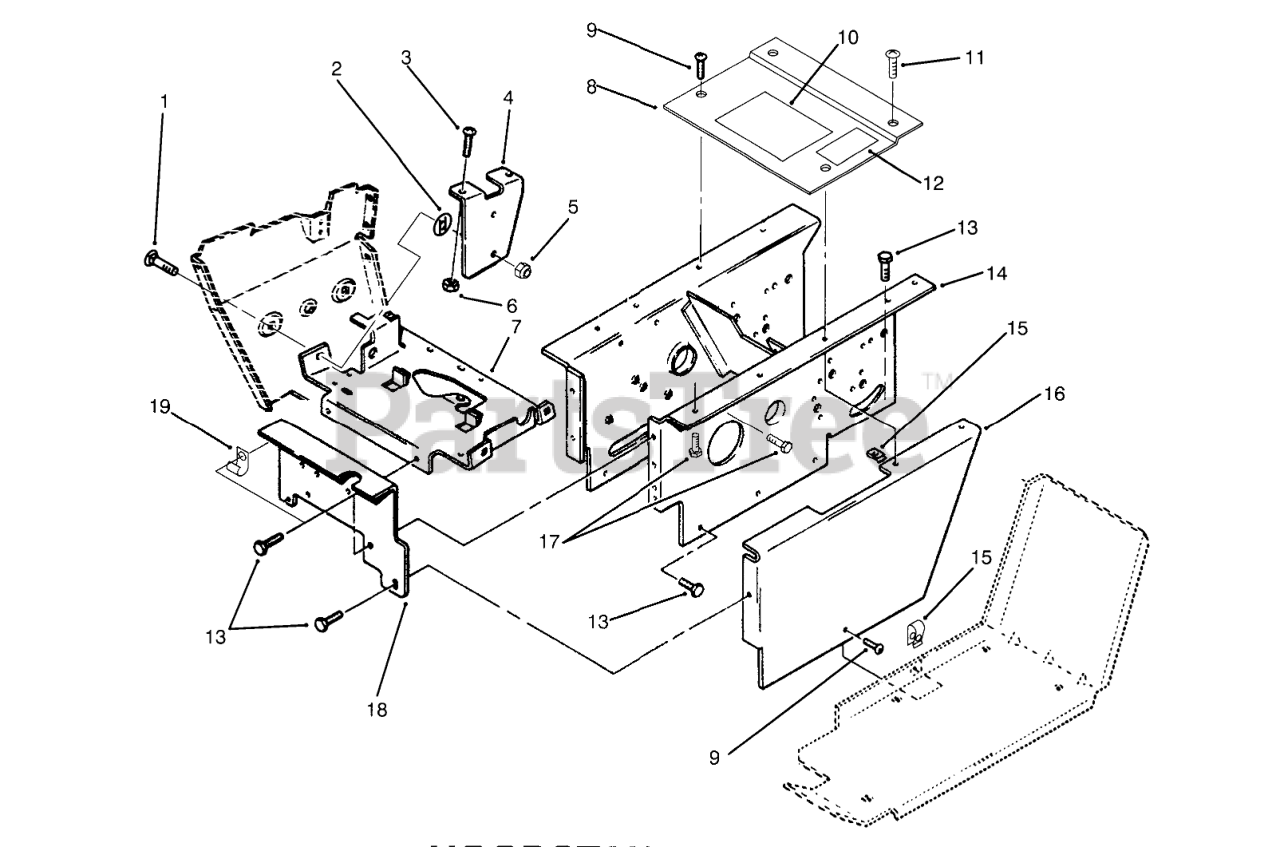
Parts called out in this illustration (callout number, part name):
1	BOLT-CARR
2	NUT-PUSH
3	SCREW-HH
4	Bracket-Holder
5	NUT-LOCK, NI
6	Nut
7	WLD-SUPPORTB
8	Plate-Hoodstand, Top (Incl. Ref. #10)
9	Screw
10	DECAL-DANGER
11	Screw
12	DECAL-PARKING BRAKE
13	SCREW
14	Hoodstand
16	Cover-Side LH
17	SCREW-HH
18	Plate-Front
19	CLIP
